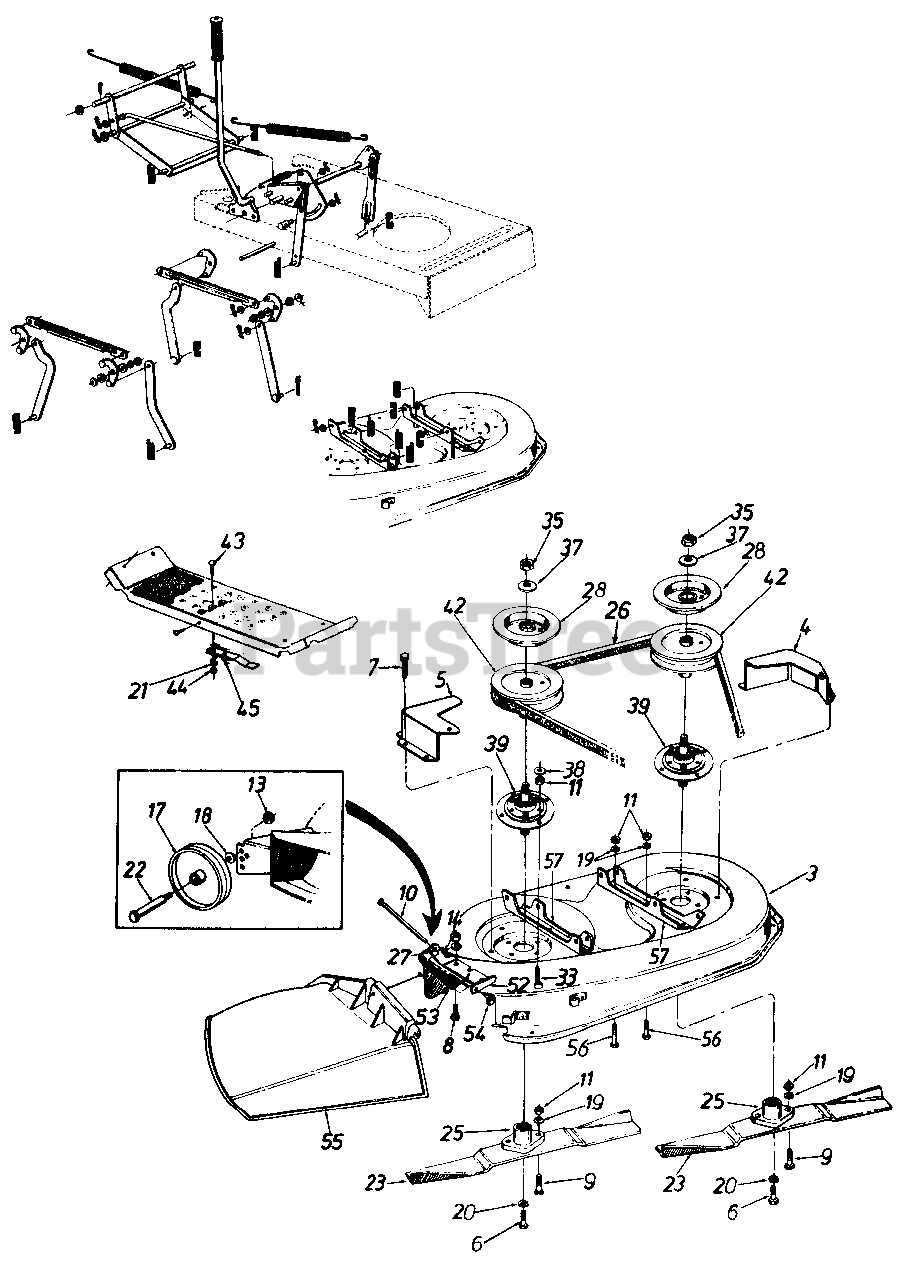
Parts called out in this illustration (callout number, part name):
3	42" Deck Ass'y.
6	Hex Bolt 3/8-24 x 1.0" Lg.
7	Hex Wash. Hd. TT-Tap Scr. 1/4-20 x .5" Lg.
8	Truss Mach. Scr. 1/4-20 x .75"
9	Hex Bolt Special 5/16-24 x 1.0"
10	Hinge Pin
11	Hex Nut 5/16-24 Thd.
13	Hex Top L-Nut 3/8-16 Thd.
14	Hex Nut 1/4-20 Thd.
17	Deck Wheel-5"
18	Bell-Wash. .40" I.D. x .88" O.D.
19	L-Wash. 5/16" I.D.
20	L-Wash. 3/8" I.D.-H.D.
21	L-Wash. 1/4" I.D.
22	Shld. Bolt .498" Dia. x 1.53"
23	High-Lift Blade
25	Blade Adapter
26	V-Belt
27	Bell-Wash. 1/4" I.D.
28	Brake Disc
33	Hex Bolt 5/16-24 x .75" Lg.
35	Hex Jam Nut 5/8-18 Thd.
37	L-Wash. 5/8" I.D.
38	L-Wash. 5/16" I.D.
39	Blade Spindle Ass'y. Comp.
42	5.5" Dia. Pulley
43	Carr. Bolt 1/4-20 x .62
44	Hex Nut 1/4-20 Thd.
45	Blade Brake Ass'y.
52	Hinge Mtg. Brkt.
53	Torsion Spring
54	Push Nut
55	Chute Ass'y. Comp.
56	Hex Bolt 5/16-24 x .75" Lg.
